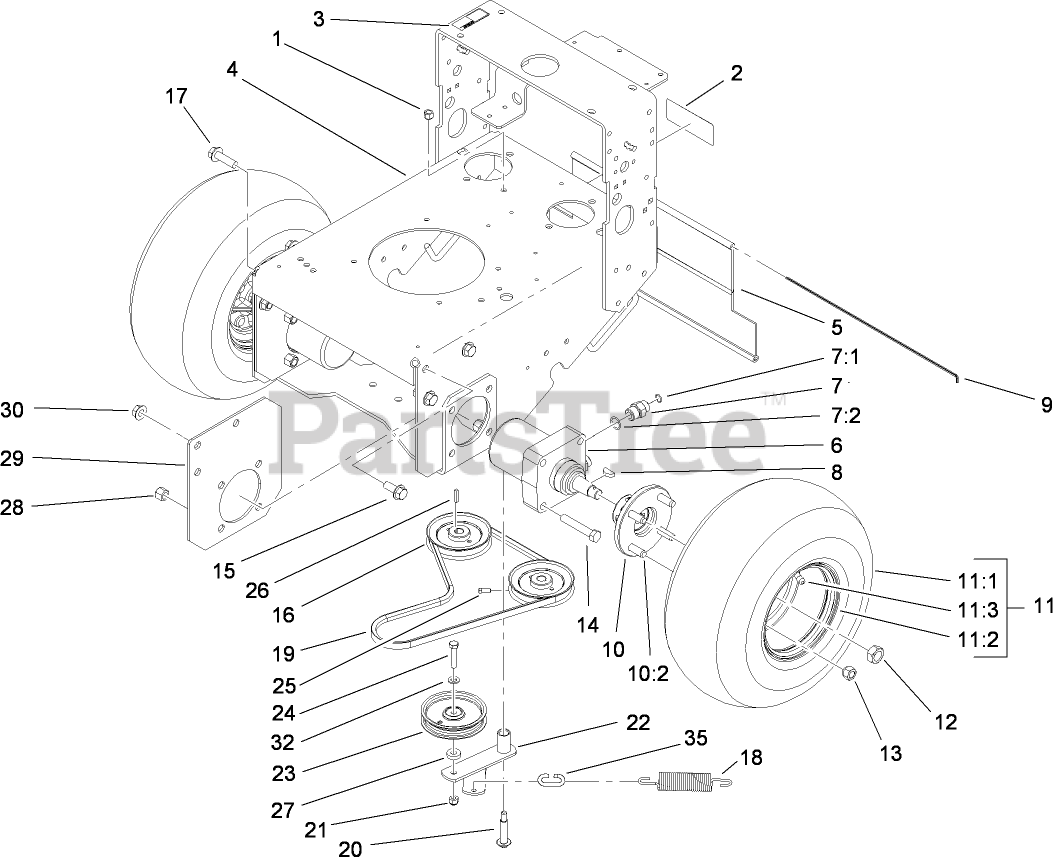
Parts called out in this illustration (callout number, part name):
1	NUT-LOCK
2	DECAL-CAUTION
3	DECAL-SHUT OFF, FUEL
4	FRAME ASM
5	SHIELD-TRAILING
6	HYD MOTOR ASM
7	FITTING-STRAIGHT
7:1	O-RING
7:2	O-RING
8	KEY-WOODRUFF
9	ROD-SHIELD
10	WHEEL HUB ASM
10:2	STUD-TYPE, DRIVE
11	WHEEL AND TIRE ASM
11:3	STEM-VALVE
12	NUT-MOTOR, WHEEL
13	NUT-LUG
14	SCREW-HH
15	SCREW-HHF
16	SHEAVE ASM
17	SCREW-HHF
18	SPRING-EXTENSION
19	BELT-V
20	BOLT-WHEEL
21	NUT-LOCK, NI
22	IDLER LEVER ASM
23	PULLEY-IDLER
24	SCREW-HH
25	SCREW-SET
27	Washer
28	NUT-HHF
29	PLATE-FRAME
30	NUT-HF
32	WASHER-FLAT
35	LINK-SPRING
